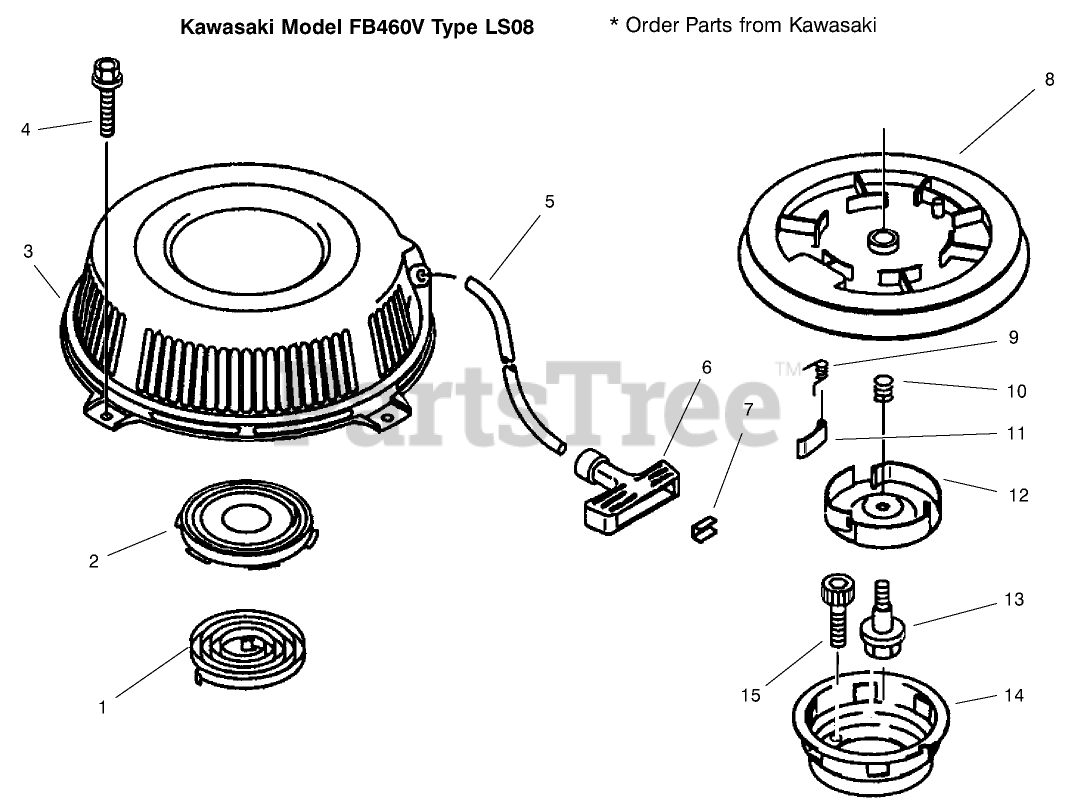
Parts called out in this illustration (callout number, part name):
1	Spring-Recoil
2	Case
3	Case-Recoil Starter
4	BOLT-FLANGED (6X10)
5	Rope
6	Grip
7	Washer
8	Reel
9	Spring
10	Spring
11	Pawl
12	Retainer
13	Bolt
14	Pulley-Starting
15	Bolt-Socket
